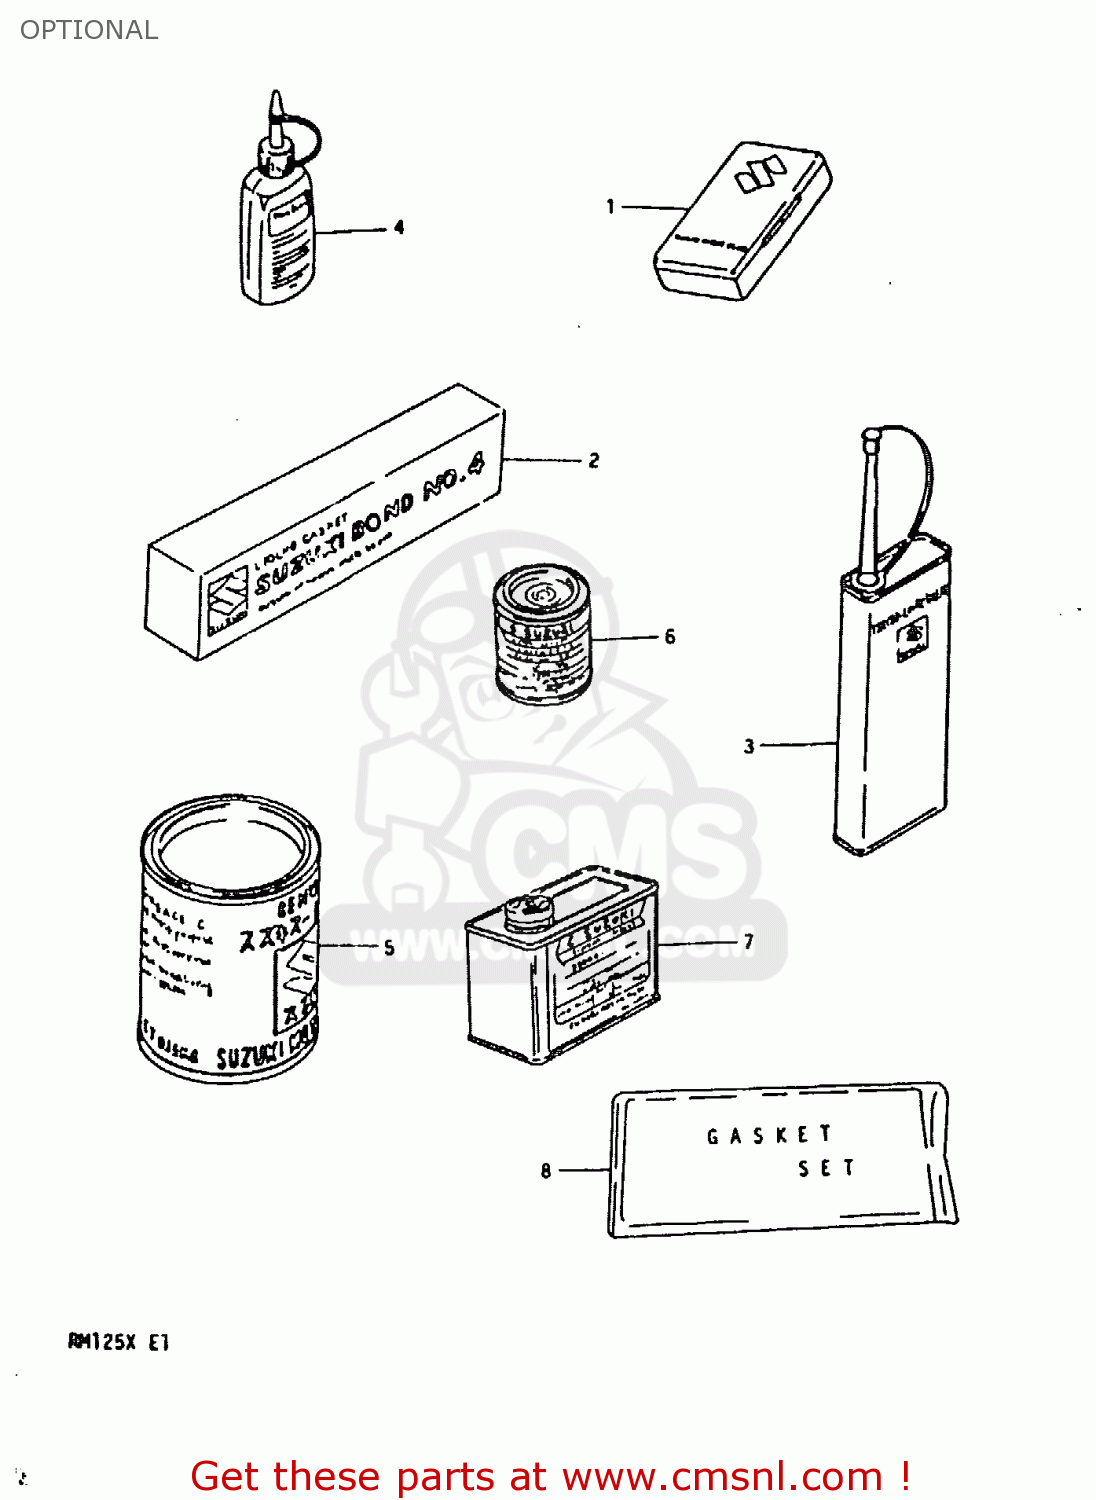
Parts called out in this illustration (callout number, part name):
1	TUBE REPARING TOOL
2	BOND 1104
3	THREAD LOCK NO.1401 CLEAR 200G
4	THREAD LOCK NO.1303B PURPL 50G
5	GREASE(C)EP2 LITHIUM 150G
6	PAINT,BLACK
7	PAINT (BLACK)
8	GASKET SET
